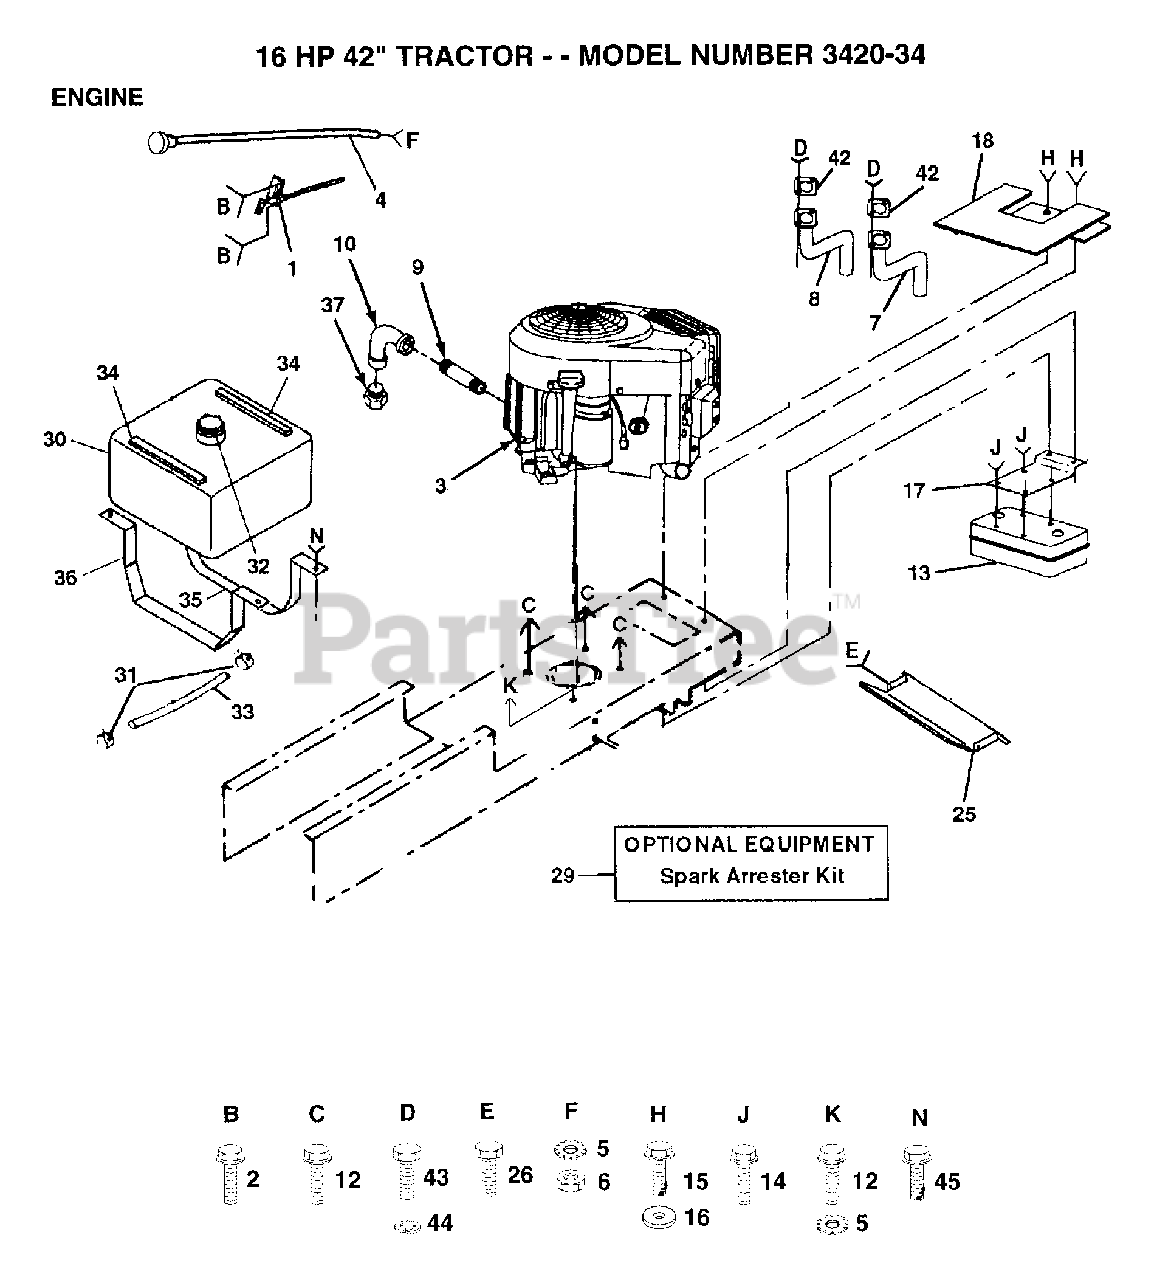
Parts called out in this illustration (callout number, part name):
2	SCREW LT
3	ENGINE B&S 16HP
4	CHOKE CONTROL
5	LOCKWASHER
8	EXHAUST ASM LH
9	PIPE NIPPLE LT
10	ELBOW
12	SCREW LT
14	SCREW ST
15	SCREW
16	WASHER
17	BRACKET MUFFLER
25	HEAT SHIELD
26	SCREW
29	SPARK ARREST KIT
31	HOSE CLAMP
34	"STRIP,FORM"
35	STRAP ASM. F.TANK
36	"STRAP,TANK"
44	LOCKWASHER
45	SCREW LT
